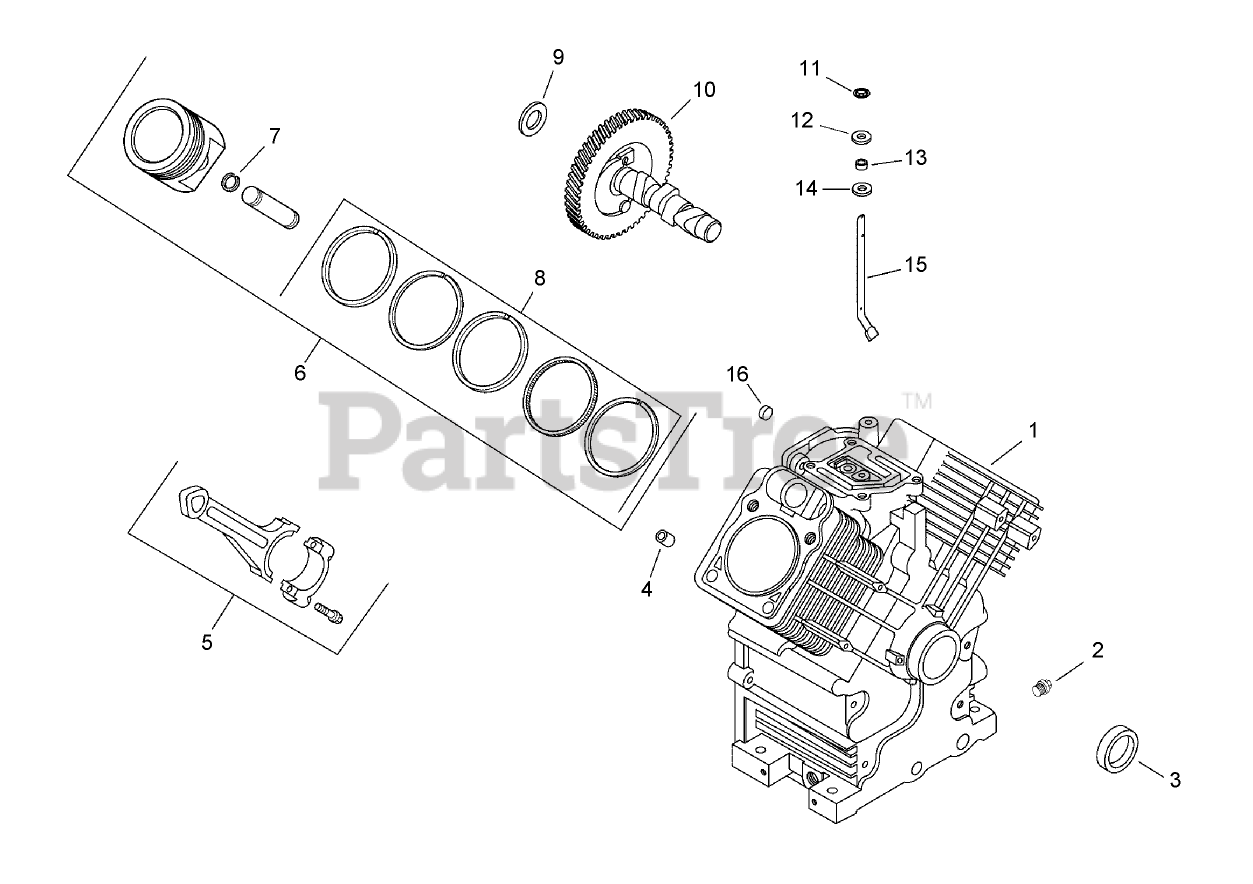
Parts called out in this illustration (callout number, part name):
2	PLUG-PIPE HEAD, 3/8
3	SEAL-OIL
4	Pin-Locating
5	Rod-Connecting (Standard)
5	Rod-Connecting (.25)
6	Piston and Ring Set (STD)
6	Piston and Ring Set (.08)
6	Piston and Ring Set (.25)
6	Piston and Ring Set (.50)
7	RETAINER-PIN, PISTON
8	Ring Set (.25)
9	SHIM-CAMSHAFT (RED .032)
9	SHIM-CAMSHAFT (BLACK .04)
9	SHIM-CAMSHAFT (WHITE .028)
9	SHIM-CAMSHAFT (BLUE .03)
9	SHIM-CAMSHAFT (YELLOW .034)
9	SHIM-CAMSHAFT (GREEN .036)
9	SHIM-CAMSHAFT (GRAY .038)
10	Camshaft
11	RETAINER-RING
12	Washer (Top)
13	SEAL-CROSS SHAFT, GOVERNOR
14	Washer (Bottom)
15	SHAFT-CROSS, GOVERNOR
16	PLUG-CUP
